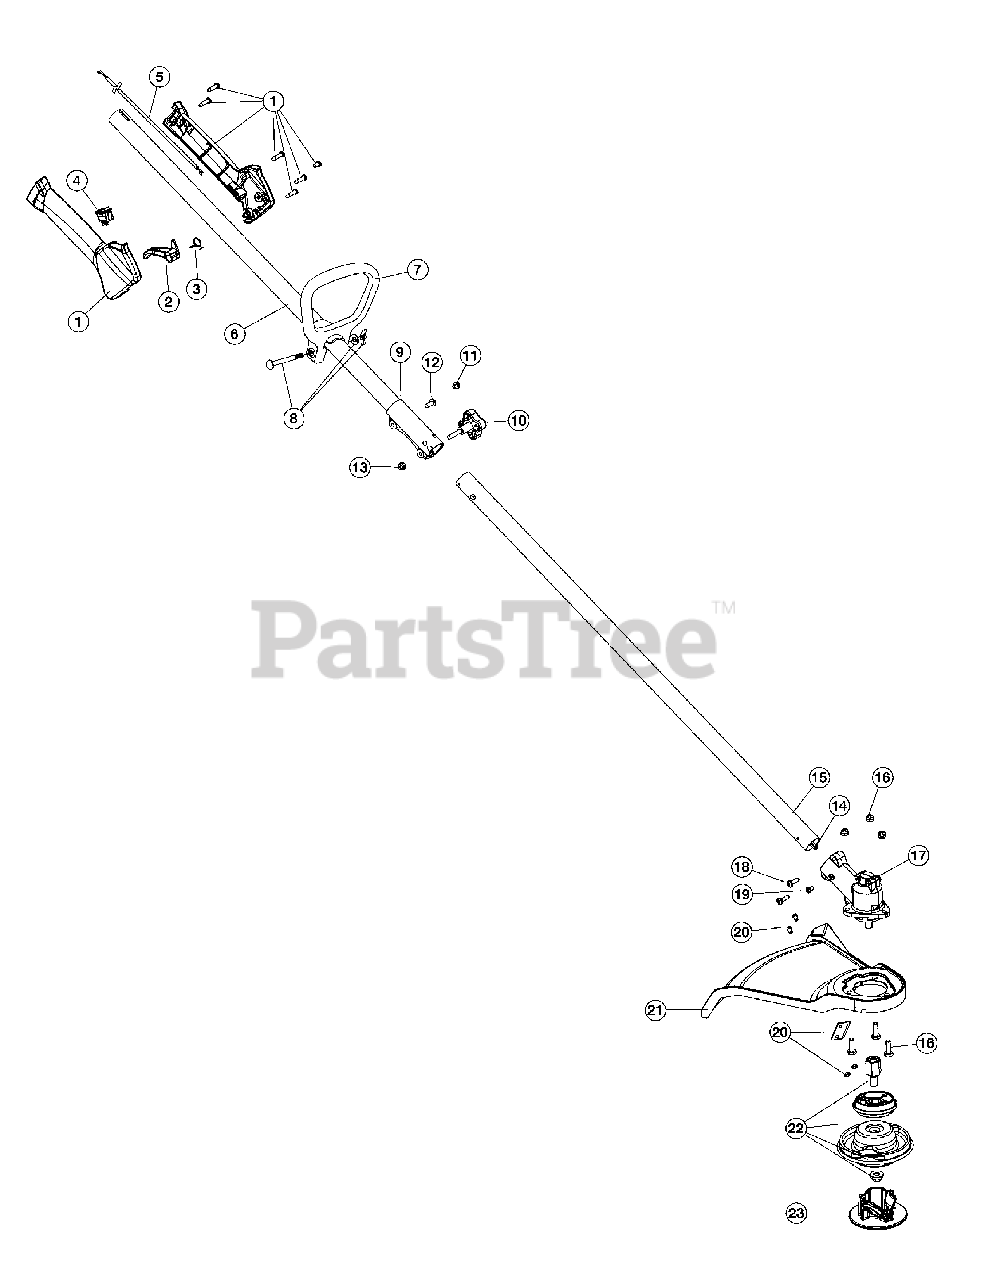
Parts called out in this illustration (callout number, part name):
1	Throttle Housing Assembly
2	Throttle Trigger
3	Throttle Trigger Spring
4	Switch Assembly
5	Throttle Cable Assembly
6	Upper Drive Shaft Housing
7	D-Handle Assembly
8	D-Handle Hardware
9	Split Boom Coupler
10	Adjustment Knob
13	Nut
14	Lower Flexible Drive Shaft
15	Lower Drive Shaft Housing
16	Shield Mount Screw Assembly
17	Gearbox Assembly
18	Gearbox Screw
19	Anti-Rotation Screw
20	Blade Assembly
21	Shield Assembly
22	Cutting Head Assembly
23	Cutting Head Cap
